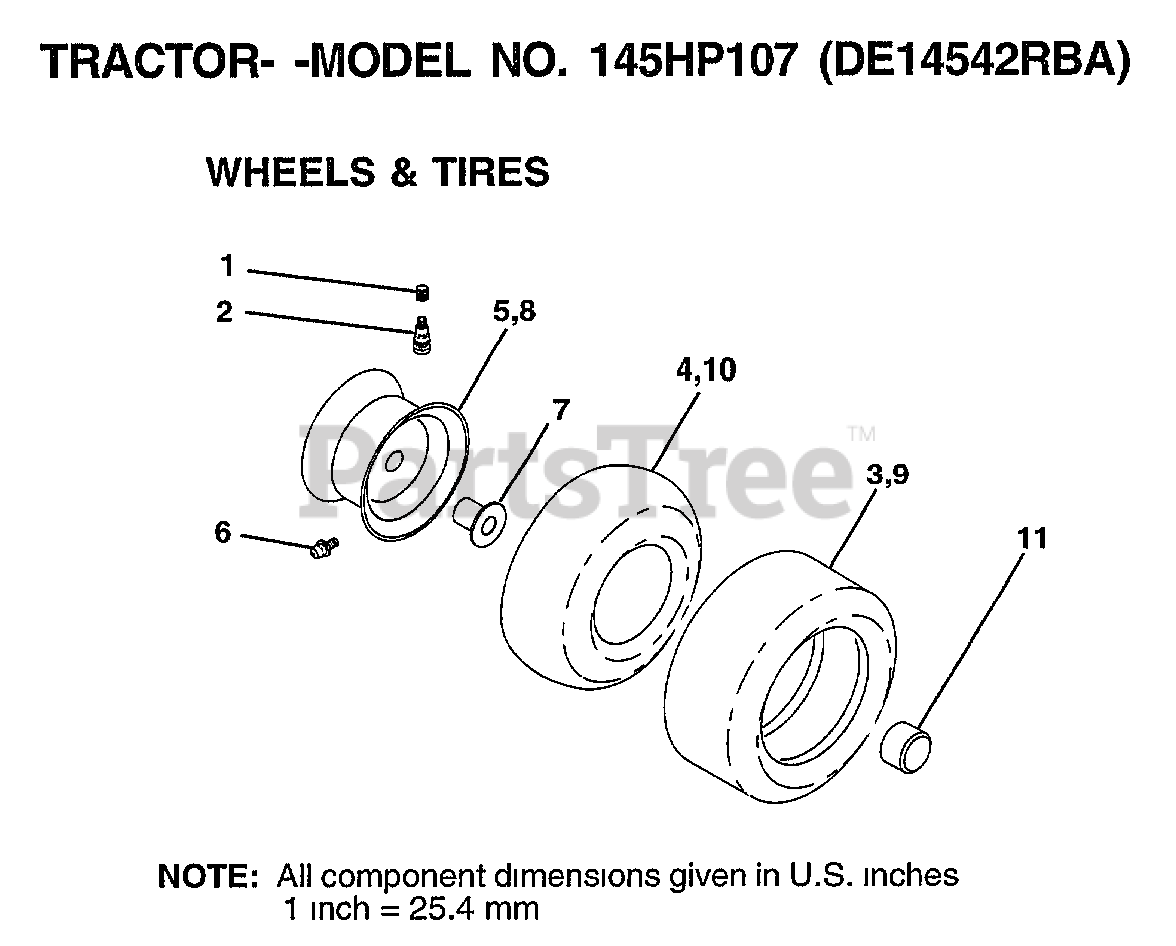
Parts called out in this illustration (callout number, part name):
1	VALVE CAP
2	VALVE STEM LT
4	TUBE.5.3/4.5/6
5	"RIM,FRT T"
6	FITTING LT
7	"FLANGE, BEARING"
8	"RIM 8"""
10	TUBE.18X9.5-8
11	HUB CAP
